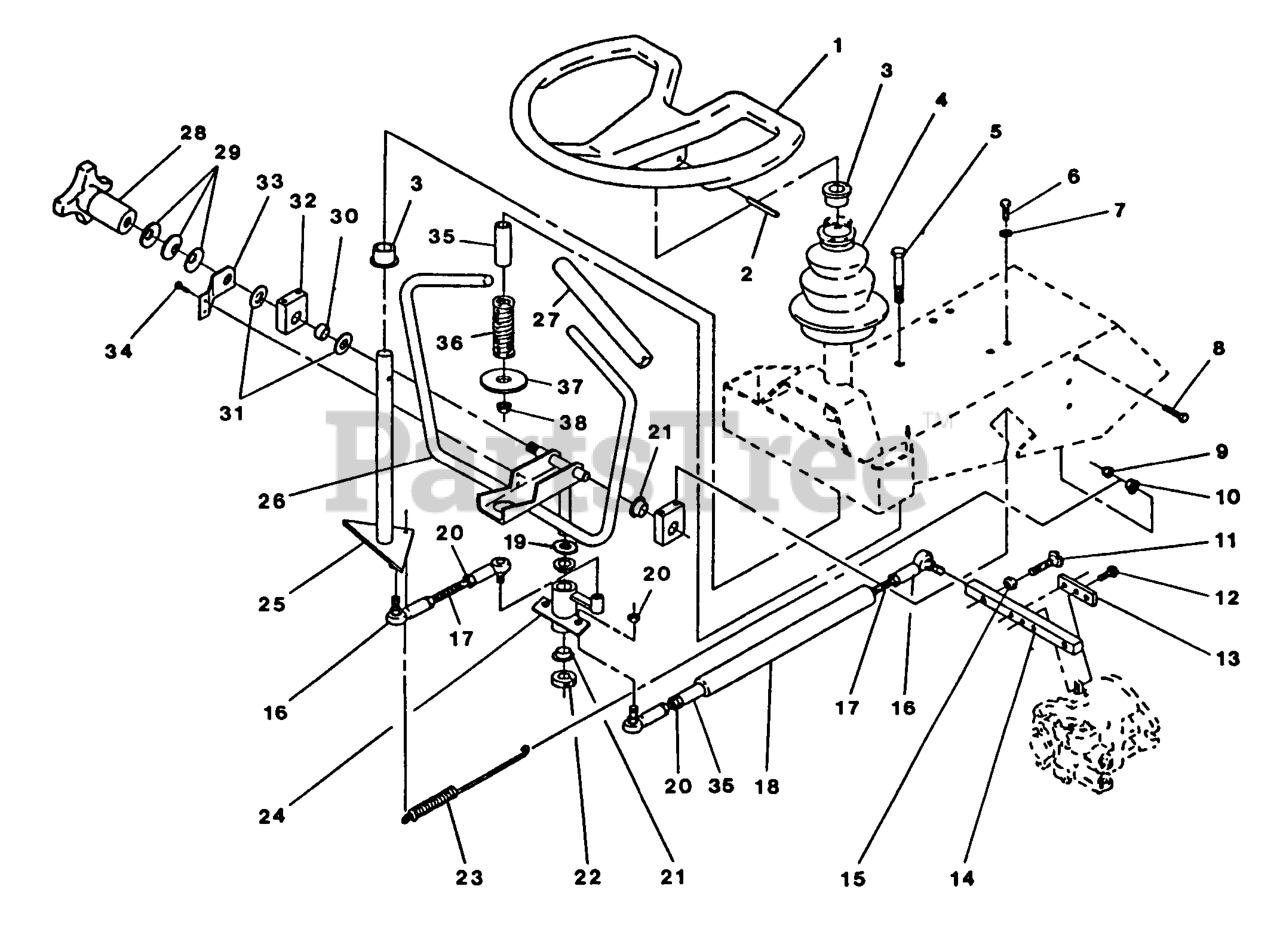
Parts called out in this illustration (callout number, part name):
7	WASHER-LOCK
13	PLATE,CLAMP
14	ARM,PUMP CONTROL
16	BALLJOINT
17	ROD,STEERING
21	BEARING-CONTROL
30	BEARING,CONTROL MOUNT
35	BUSHING,SPRING GUIDE
36	SPRING-INDICATOR, REVERSE
37	WSHR,REVERSE INDICATOR
